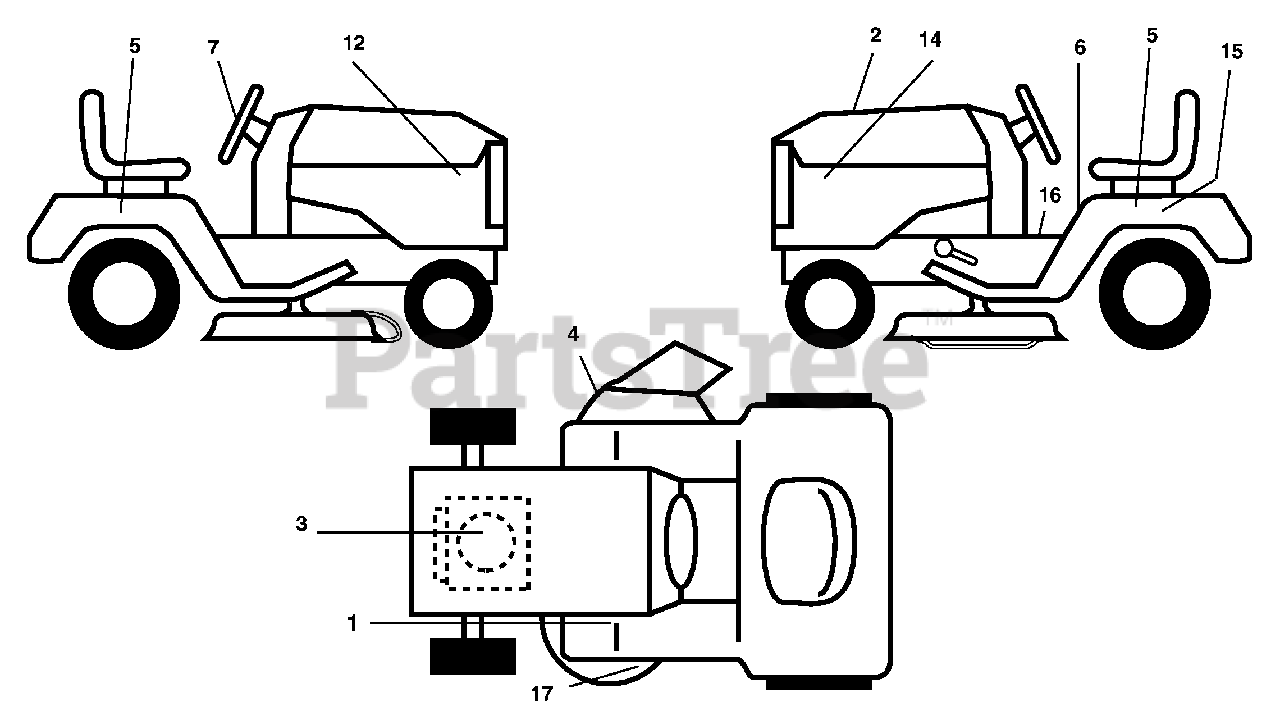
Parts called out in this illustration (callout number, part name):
1	Decal, Clutch/Brake Eng/Fr
2	Decal, Replacement
3	Decal, Engine HP
4	Decal Warning
5	Decal 5-Speed
6	Decal, Fender Danger English
7	Decal Ins Str Wh
12	Decal, Hood RH
14	Decal, Hood LH
15	Decal, Caution, Battery
16	Decal, Oper Sdl P/L Gear Dr Eng
17	Decal, V-Belt Sch.
